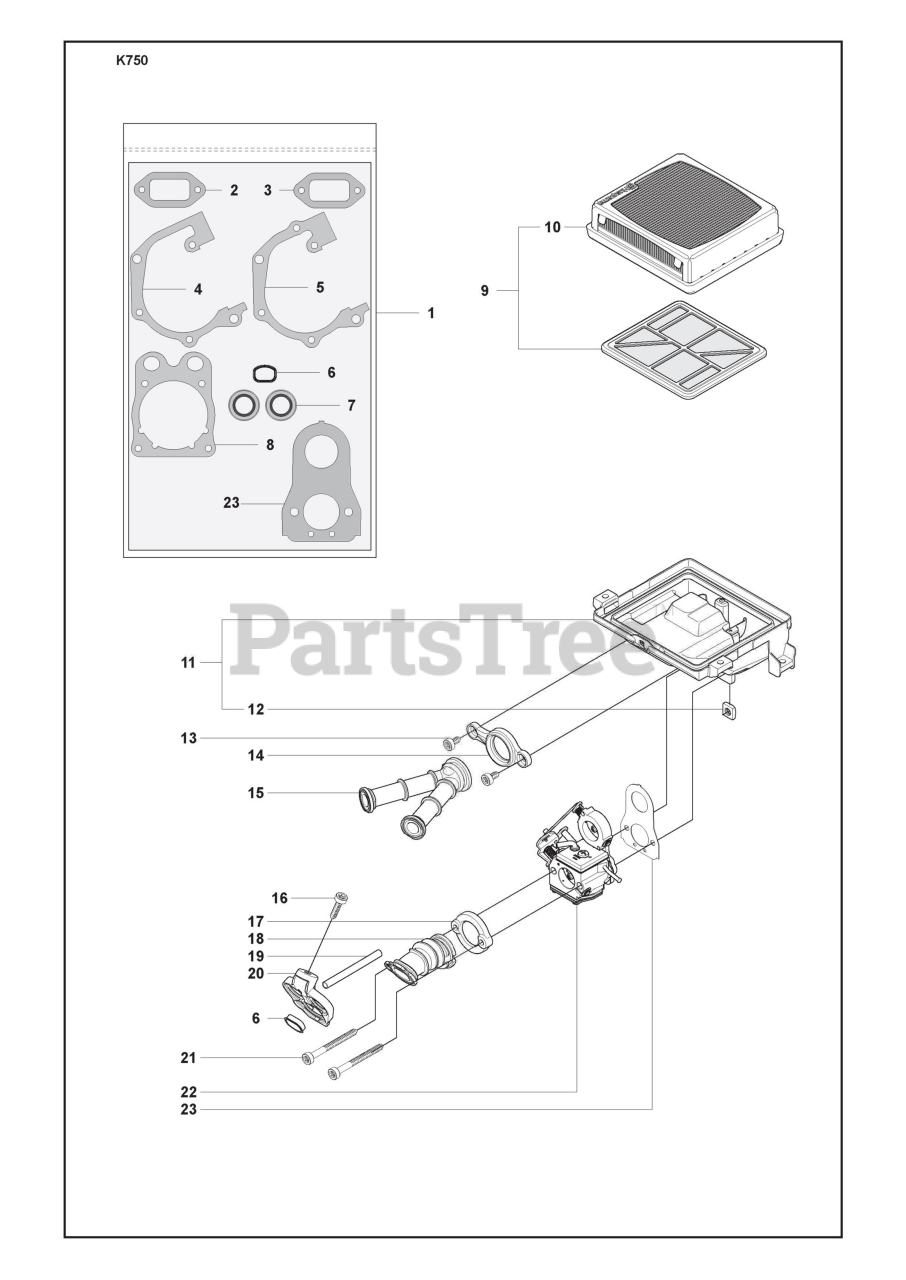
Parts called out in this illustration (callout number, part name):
1	GASKET KIT
3	GASKET MUFFLER
4	GASKET CRANKCASE
5	GASKET CRANKCASE
7	SEALING RING
8	CYLINDER BASE GASKET
9	FILTER
10	AIR FILTER PAPER
11	CARBURETTOR BRACKET
14	FLANGE INLET PIPE
15	INLET PIPE
17	FLANGE INLET PIPE
18	INLET PIPE
19	IMPULSE HOSE
22	CARBURETTOR
23	GASKET CARBURETTOR
